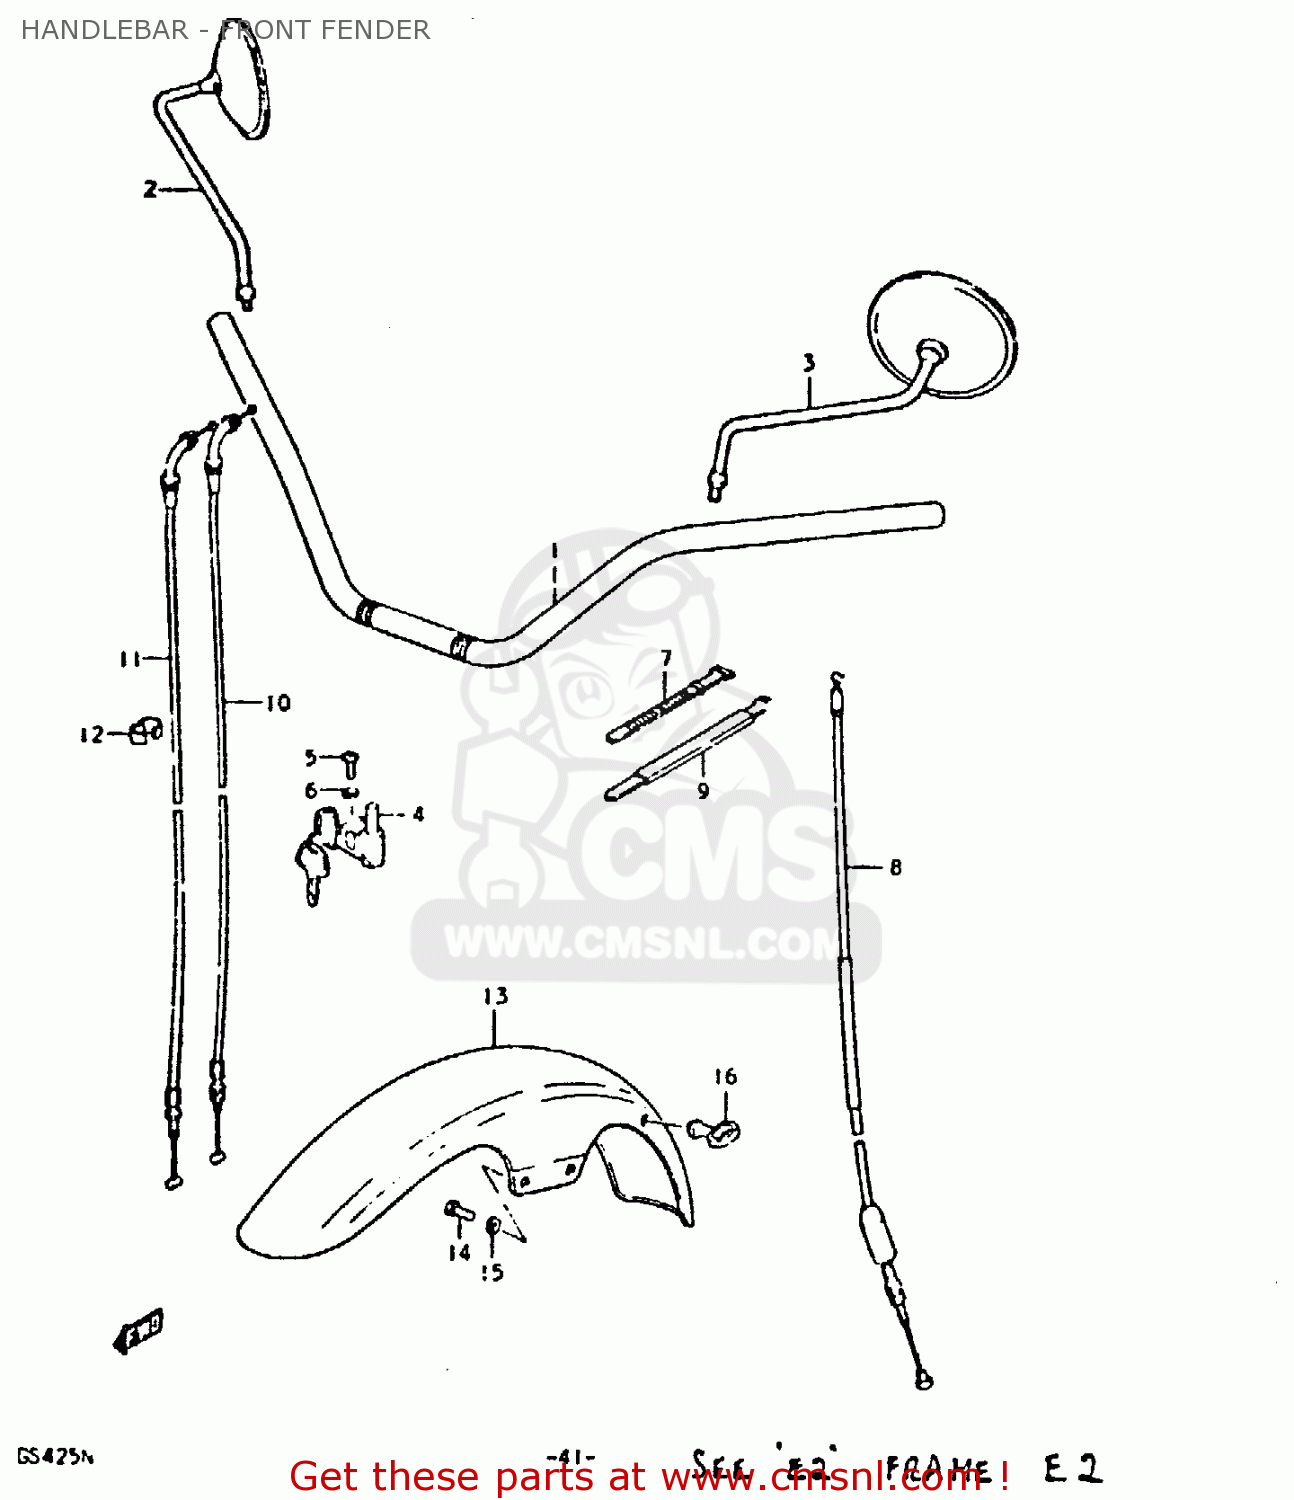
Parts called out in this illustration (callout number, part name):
1	HANDLEBAR
2	MIRROR ASSEMBLY,RIGHT
3	MIRROR ASSEMBLY,LEFT
4	LOCK ASSEMBLY,STEERING
5	SCREW
6	LOCK WASHER
7	CLAMP(L:120)
8	CABLE ASSEMBLY,CLUTCH
9	CLAMP
10	CABLE ASSEMBLY,THROTTLE
11	CABLE ASSEMBLY,THROTTLE
12	CLIP
13	FENDER,FR
14	BOLT
15	LOCK WASHER
16	GUIDE,CABLE
